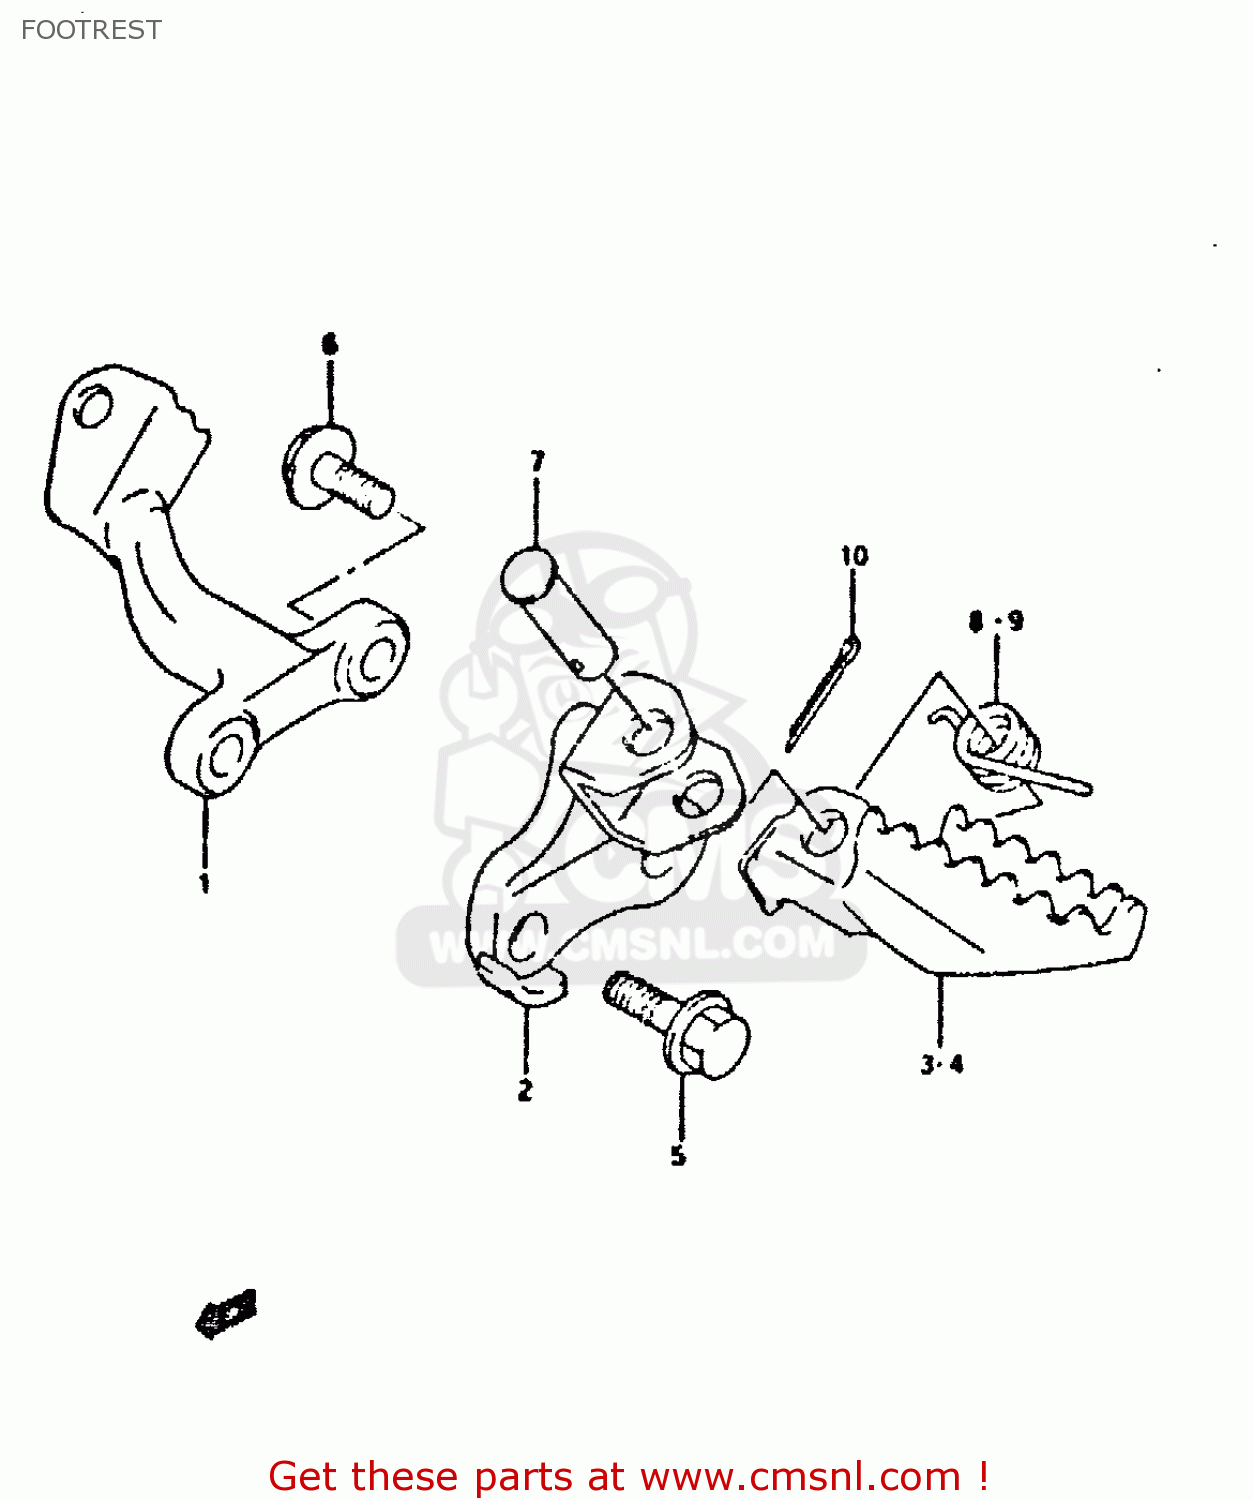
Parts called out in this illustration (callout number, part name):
1	BRACKET,FRONT FOOTREST
2	BRACKET COMP,FRONT FOOTREST
3	FOOTREST COMP,FRONT,RIGHT
4	FOOTREST COMP,FRONT,LEFT
5	BOLT
6	BOLT
7	PIN
8	SPRING
9	SPRING
10	PIN 20X20
